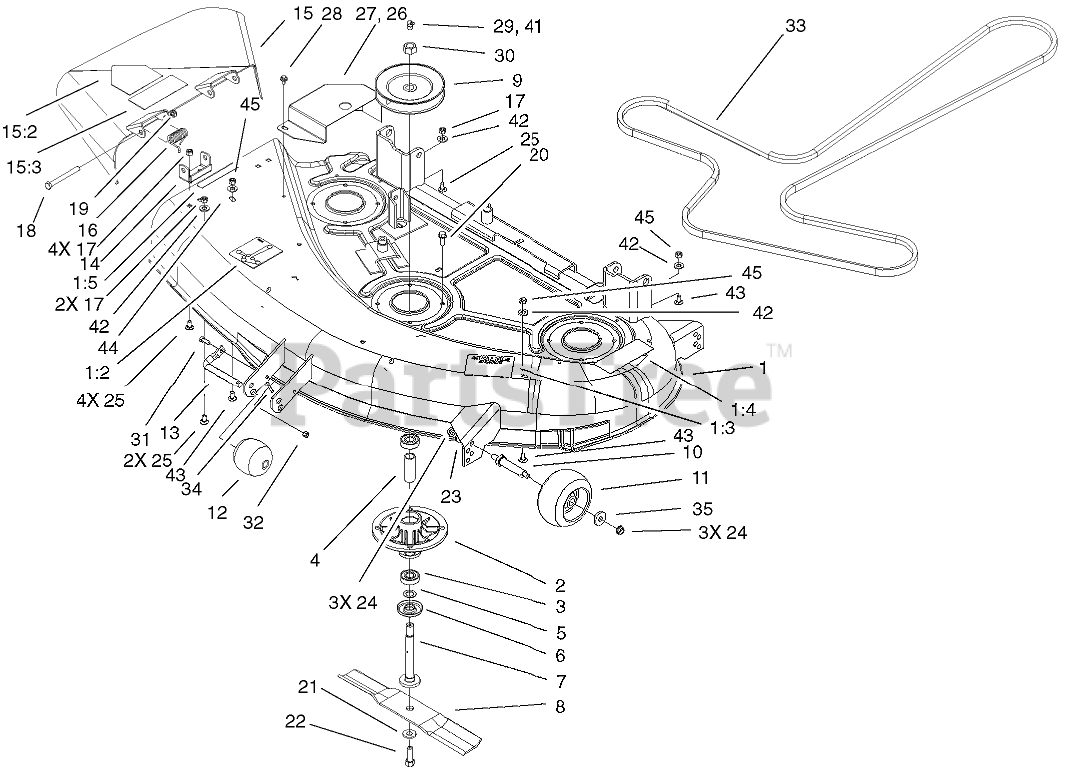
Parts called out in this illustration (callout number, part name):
1	44 INCH DECK ASM
1:2	DECAL-ROUTING, BELT
1:3	DECAL-WHEEL, GAGE
1:4	DECAL-DANGER
1:5	DECAL-CAUTION
2	HOUSING-SPINDLE
3	BEARING-BALL
4	SPACER - BEARING
5	SPACER
6	SHIELD-BEARING
7	SHAFT-CENTER, SPINDLE
9	PULLEY ASM
10	SPACER
11	WHEEL-GAGE
12	ROLLER
13	Shaft-Roller
14	BRACKET-PIVOT
15	DEFLECTOR/DECAL ASM
15:2	DECAL-DANGER
15:3	DECAL-DANGER
16	SPRING
17	NUT-LOCK, NI
18	SCREW-HH
19	NUT-HEX
20	SCREW-TAPTITE
21	WASHER-BELLEVILLE
22	SCREW-HH
23	WASHER-BELLEVILLE
24	NUT-HHF, WHIZ
25	SCREW-CARR
26	COVER-BELT, LH
27	COVER-BELT, RH
28	SCREW-HHFTF
29	FITTING-GREASE
30	NUT-HEX
31	SCREW-HH
32	NUT-LOCK, NI
33	V-BELT, DRIVE
34	PIN-COTTER
35	WASHER
41	FITTING-GREASE
42	WASHER-FLAT
43	SCREW-CARR
44	WASHER-FLAT
45	NUT-LOCK, NI
